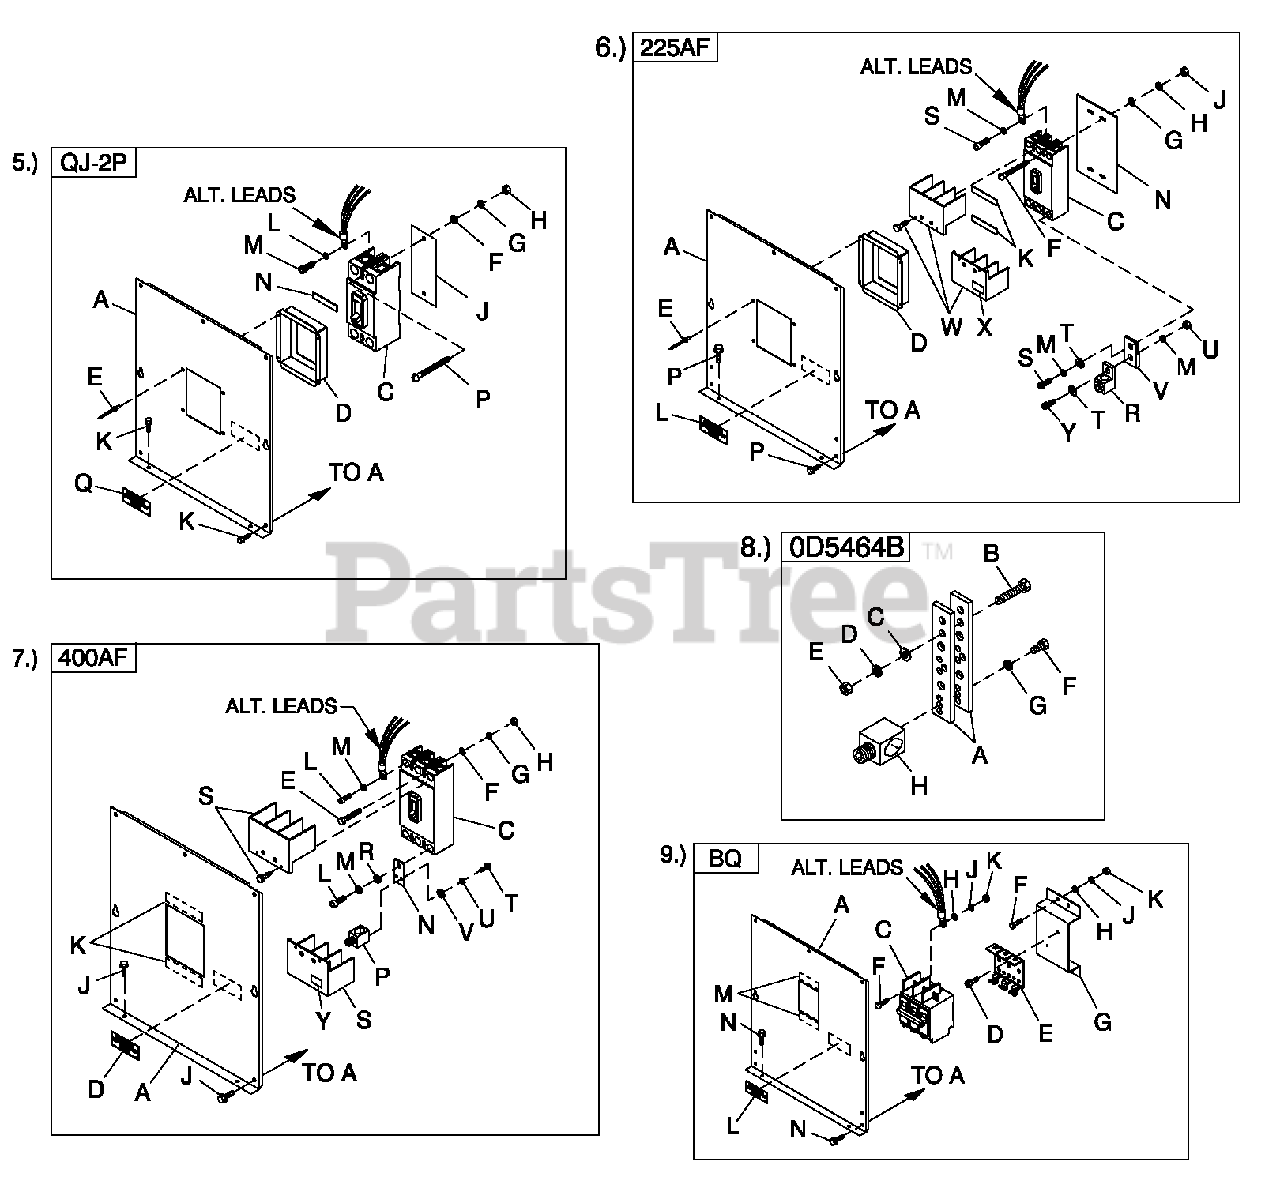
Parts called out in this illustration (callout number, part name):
A	COVER QJ 2P FRM CB
C	CB 0225A 240V 2P S QJ22
D	COVER QJ 2P CB DISH
E	RIVET POP.125X.275SS
F	WASHER FLAT 1/4-M6 ZINC
G	WASHER LOCK M6-1/4
H	NUT HEX 1/4-20 STEEL
J	INSULCB2P QJ
K	SCREW THF M6-1 X 16 N WA Z/JS
L	WASHER LOCK 3/8
M	SCREW SHC 3/8-16 X 3/4 G8.8 NZ
N	TAPE ELEC 1/2 FOAM (AS REQ' D)
P	SCREW RHM 1/4-20X3
Q	DECAL CUSTOMER CONNECT INSI DE
A	COVER CBC2-C4 225AF
C	CIRCUIT BREAKERS 200A FRAME
D	COVER CB DISH 225AF
E	RIVET POP .125X .275 SS
F	SCREW RHM #8-32X3-1/4
G	WASHER FLAT #8 ZINC
H	WASHER LOCK #8-M4
J	NUT HEX #8-32 STEEL
K	TAPE ELEC 1/2 FOAM
L	DECAL CUSTOMER CONNECT INSI DE
M	WASHER LOCK M8-5/16
N	INSULATOR CB225AF
P	SCREW THF M6-1 X 16 N WA Z/JS
R	LUG SLDLSS 300 MCM-6 AL/CU
S	SCREW SHC M8-1.25X20G8
T	WASHER FLAT 5/16-M8 ZINC
U	NUT HEX M8-1.25 G8 CLEARZINC
V	BUS BAR 200A LUG A DAPTOR
W	TERMINAL COVER CB
X	DECAL TERMINAL SHOCK HZ D BI
Y	SCREW SHC M8-1.25 X 25 G12.9
A	COVER CBC2-C4 400AF
C	CIRCUIT BREAKERS 400A FRAME
D	DECAL CUSTOMER CONNECT INSI DE
E	SCREW RHM 10-32X4
F	WASHER FLAT #10 ZINC
G	WASHER LOCK #10
H	NUT HEX #10-32 STEEL
J	SCREW THF M6-1 X 16 N WA Z/JS
L	SCREW SHC M10-1.5X 25 G12.9
M	WASHER LOCK M10
N	BUS BAR CB A DAPTER 225-400 A
P	LUG SL DLSS 600/250-1/0 X 1/4-28
S	TERM COVER CB
T	SCREW HHC 1/4-28 X 1/2 G5
U	WASHER LOCK M6-1/4
V	WASHER FLAT 1/4-M6 ZINC
W	SCREW SHC M10-1.5X 25 G12.9
X	WASHER LOCK M10
Y	DECAL TERMINAL SHOCK HZ D BI
A	BUS BAR NEUTRAL BLOCK 390
B	SCREW HHC M8-1.25X 45 G8.8 FT
C	WASHER FLAT 5/16-M8 ZINC
D	WASHER LOCK M8-5/16
E	NUT HEX M8-1.25G8YELCHR
F	SCREW HHC 1/4-28 X 3/4 G5
G	WASHER LOCK 1/4-M6SS
H	LUG SL DLSS 600/250-1/0 X 1/4-28
A	COVER BQ CIR BREAKER CPL 3P
C	CB 0125A 2P 240V S BQ2 LL
D	SCREW PHTT M4-0.7 X 10 ZYC
E	BRKTCBMTG BACK
F	SCREW RHM #10-32X3/4
G	BRKT BQCBSTANDOFF
H	WASHER FLAT #10 ZINC
J	WASHER LOCK #10
K	NUT HEX #10-32 STEEL
M	TAPE ELEC 1/2 FOAM
N	SCREW THF M6-1 X 16 N WA Z/JS
